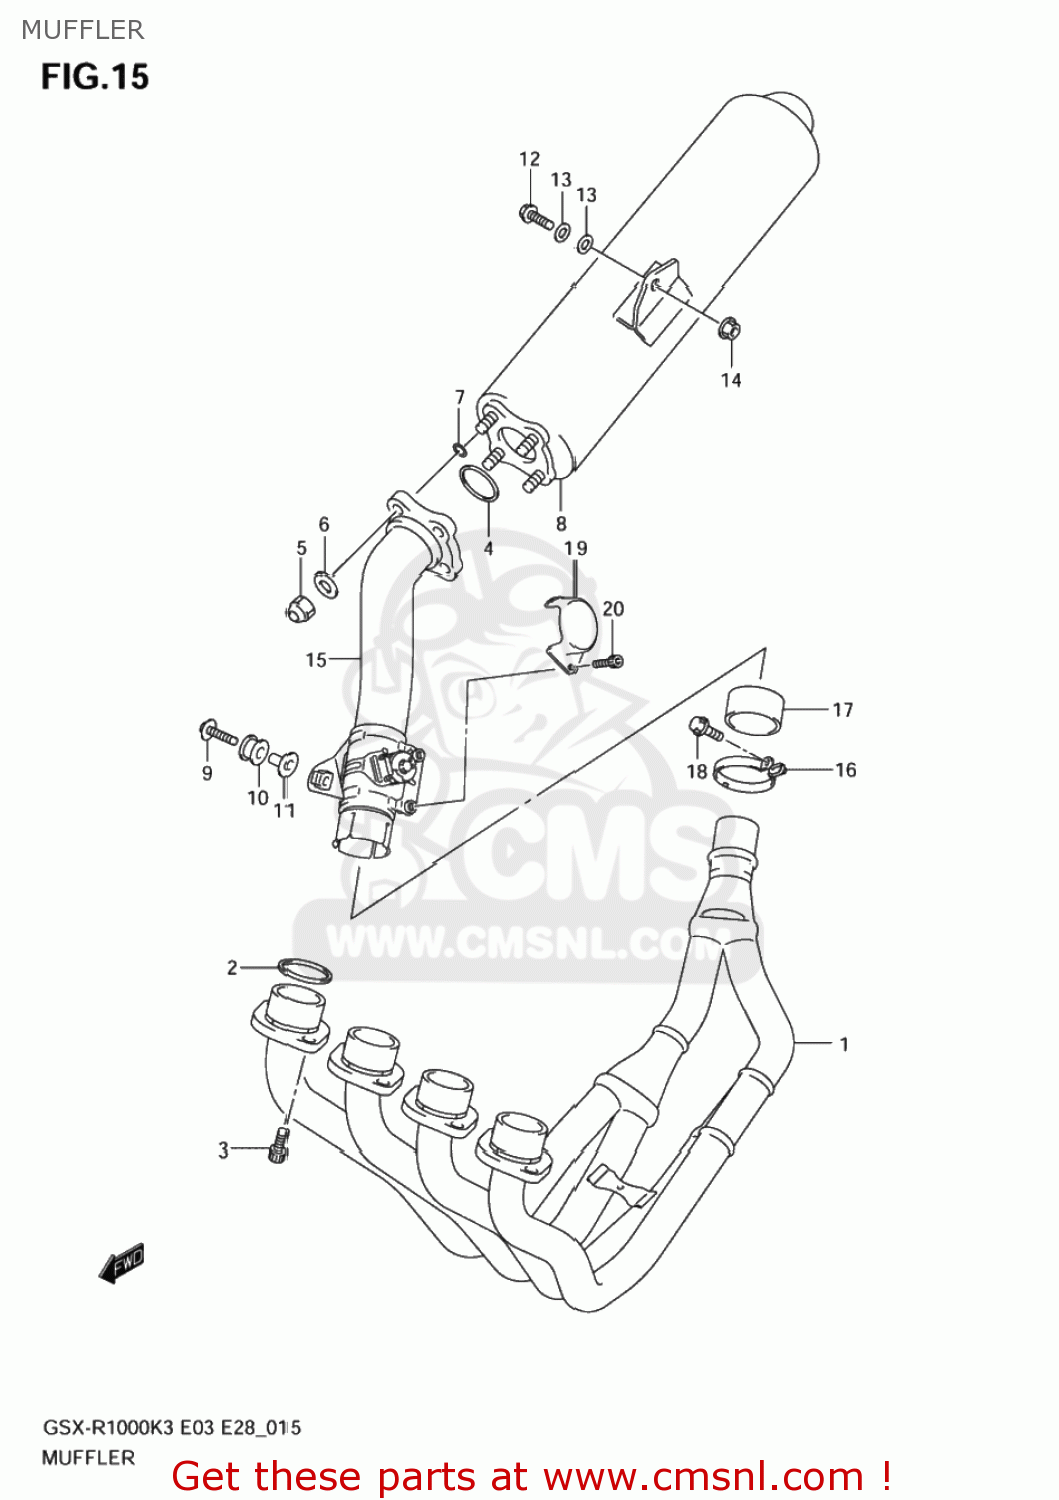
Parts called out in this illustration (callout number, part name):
1	EXHAUST
2	GASKET,EXHAUST PIPE
3	BOLT
4	GASKET,MUFFLER JOINT (NAS)
5	NUT
6	WASHER(8.5X18X1.6)
7	O RING(D:1.9,ID:7.8)
8	BODY,MUFFLER
9	BOLT 8X45
10	CUSHION
11	SPACER(8.6X12X24.2)
12	BOLT(8X40)
13	WASHER(8.5X23X1.5)
14	NUT
15	JOINT COMP
16	CLAMP,CONNECTOR
17	CONNECTOR,JOINT
18	BOLT
19	COVER,EXHAUST VALVE
20	BOLT(6X12)
